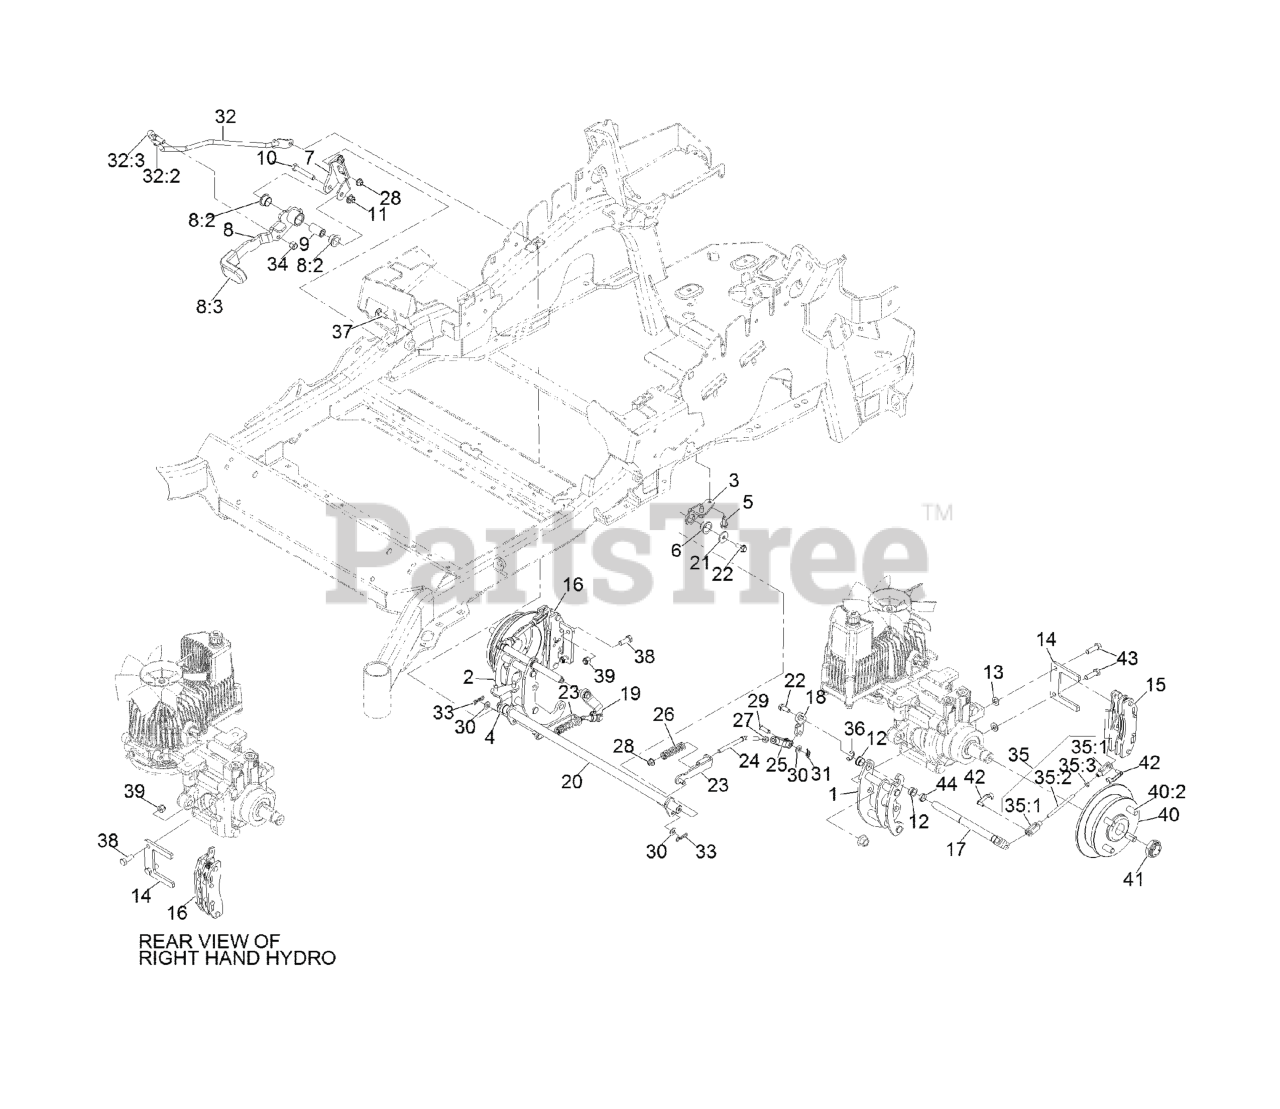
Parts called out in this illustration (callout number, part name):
1	MOUNT-BELLCRANK, LH
2	MOUNT-BELLCRANK, RH
3	MOUNT-PIVOT, LH
4	MOUNT-PIVOT, RH
5	Screw-HWH 5/16-18 X 3/4 Tf
6	BUSHING-FLANGE
7	BRACKET-MOUNT
8	BRAKE LEVER ASM W/ GRIP
8:2	BUSHING-FLANGE
8:3	GRIP-LEVER
9	HANDLE-PIVOT, BRAKE
10	SCREW-HH
11	NUT-HF, NI
12	BUSHING
13	WASHER-FLAT
14	PLATE-MOUNT, BRAKE
15	CALIPER-BRAKE
16	CALIPER-BRAKE, RH
17	BELLCRANK
18	ARM-INNER, LH
19	ARM-INNER, RH
20	SHAFT-CROSS
21	WASHER-FLAT
22	SCREW-HHF
23	BRACKET-L
24	LINKAGE-MID
25	YOKE-OFFSET
26	SPRING-COMPRESSION
27	NUT-JAM
28	NUT-HF, NI
29	PIN-CLEVIS
30	WASHER-PLAIN
31	PIN-COTTER, LOCKING
32	FRONT LINKAGE ASM
32:2	END-TIE ROD, RH
32:3	NUT-HJ
33	PIN-COTTER, LOCKING
34	NUT-LOCK
35	REAR LINKAGE ASM
35:3	NUT-JAM
37	BOLT-CARR
38	SCREW-HH
39	NUT-LOCK, NI
40	WHEEL HUB ASM
40:2	STUD-WHEEL
41	LOCKNUT
42	PIN-CLEVIS, SPRING
43	SCREW-LOCK, PATCH
